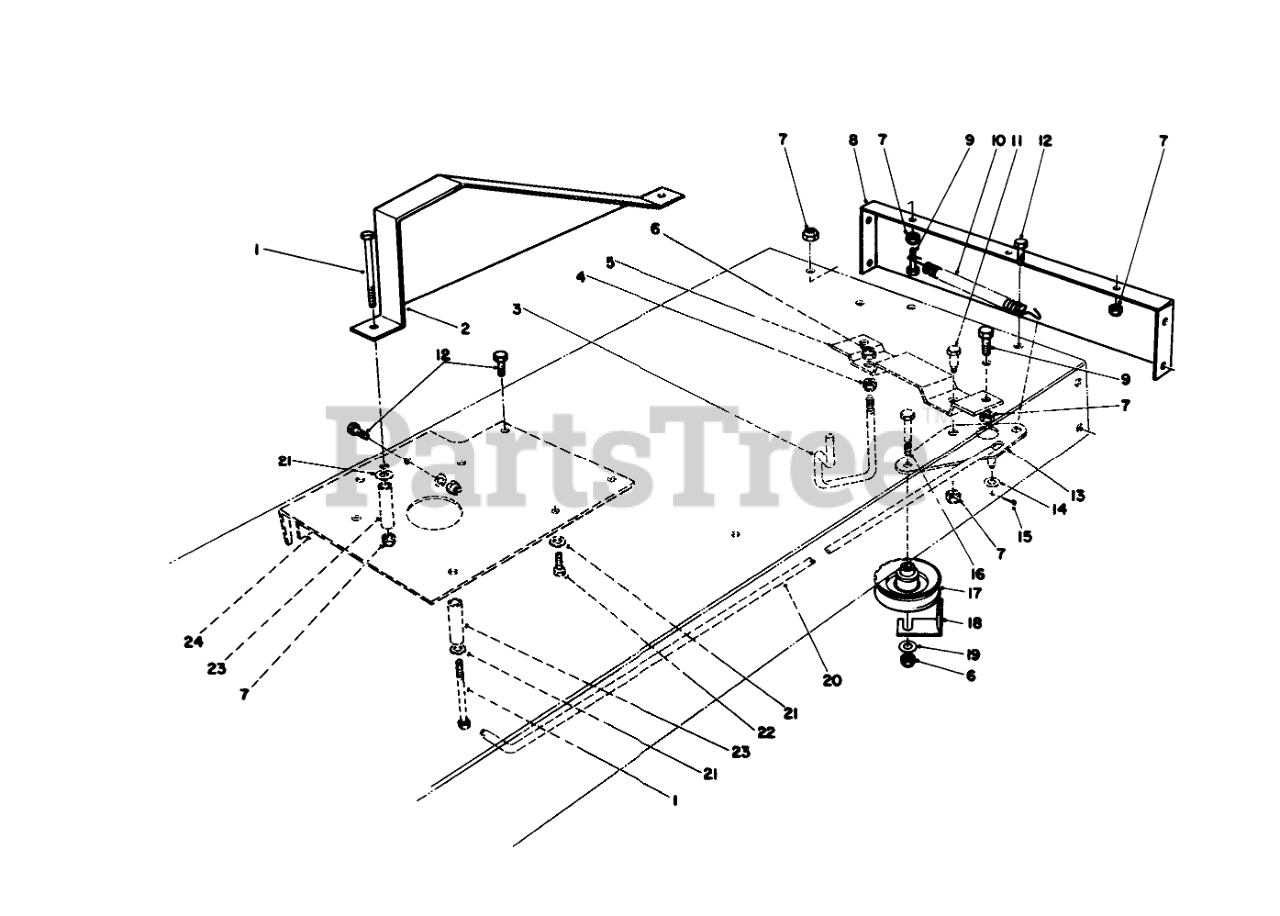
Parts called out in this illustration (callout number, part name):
1	SCREW-HH
2	CHAIN GUARD R
3	BELT GUIDE
4	NUT-LOCK, SIDE
5	TRACT SUPP BRKT B
6	NUT-LOCK, CONE
7	NUT-LOCK, NI
8	REAR FRAME R
9	SCREW-HH
10	TRACTION SPRING
11	BOLT-SHOULDER
12	SCREW-HH
13	TRACTION PIVOT BRKT
14	WASHER-FLAT
15	PIN-COTTER
16	SCREW-HH
17	PULLEY-IDLER
18	RETAINER-BELT
19	WASHER-FLAT
20	TRACTION ROD
21	WASHER-PLAIN
22	Screw-HH
23	OUTER TUBE SPACER
24	REINF PLATE R
